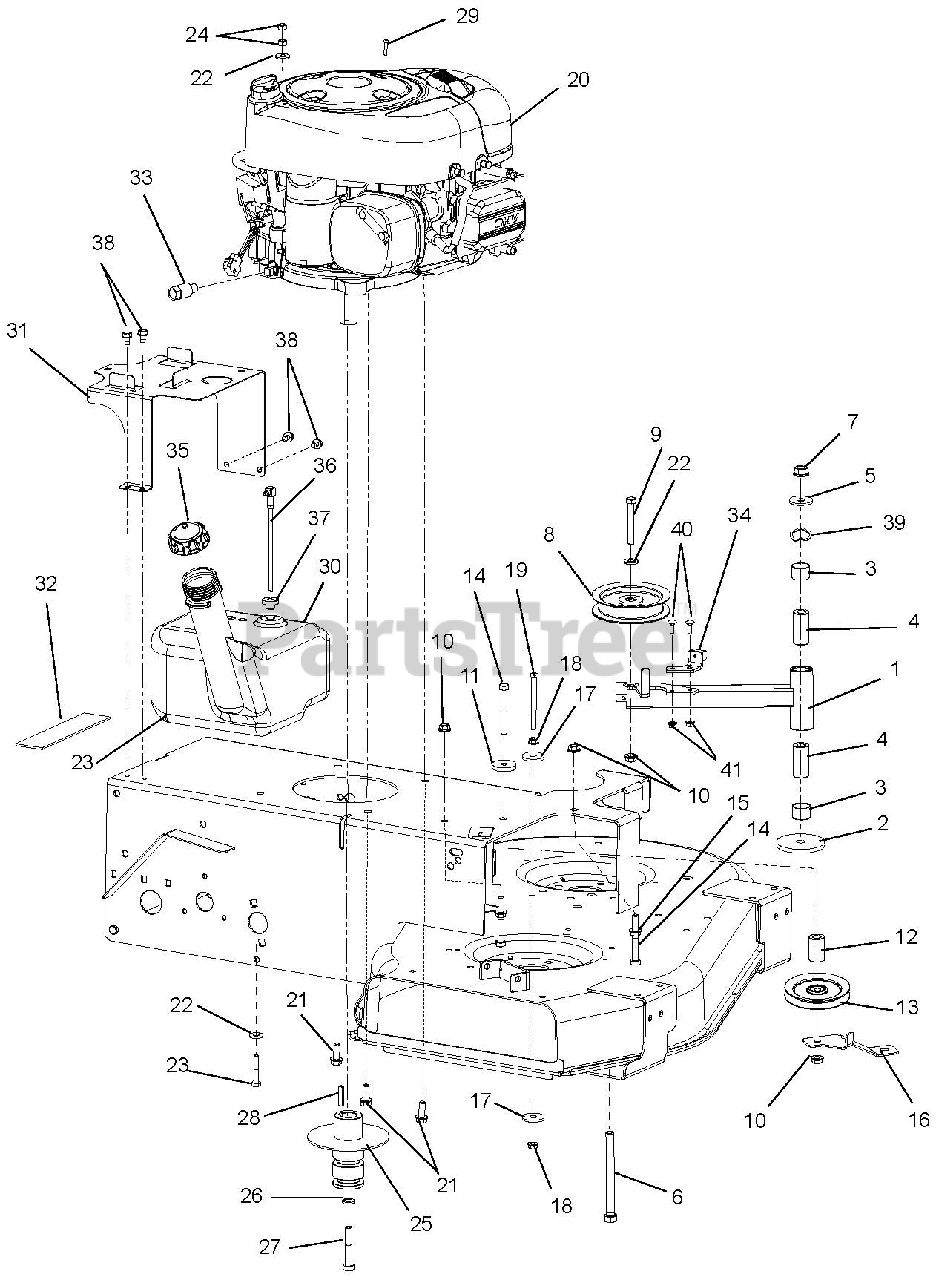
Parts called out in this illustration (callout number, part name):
1	WLDMT, PTO IDLER ARM
2	WASHER, FLAT .531X3.000X.25
3	BRG, 1.00 X 1.12 X .75
4	BSHG, SPCR .502X.997X2.03 PM
5	WSHR-FL-STL.511X1.441X.125 YWZ
6	@BLT-HEX .50-13X5.50 GR5YWZC
7	@NUT-LK-TOP-FLG .50-13 YWZC
8	ASM, IDLER 4"
9	@BLT-HEX .38-16X2.75 GR5 YWZC
10	@NUT-LK-TOP-FLG .38-16 YWZC
11	WSHR,FLT STL.406X1.50X.245YWZC
12	SPACER, .437X1.0X1.23
13	SHV, .38"ID X 4.00"OD V-IDLER
14	@BLT-HEX .38-16X3.00 GR5 YWZC
15	@NUT-SPNLK-FLG .375-16 YWZC
16	BRKT-IDLER BRACE
17	WSHR-FL-STL .406X1.375X.135 YZ
18	@NUT-SPNLK-FLG .312-18 YWZC
19	@BLT-HEX .31-18X3.50 GR5 YWZC
20	ENGINE, 13.5HP BRIGGS IC
21	@SCR-TAP .38-16X1.00 HWH TR YZ
22	@WSHR-FL-STL.38X.875X.083 YWZC
23	@BLT-HEX .31-18X1.75 GR5 YWZC
24	@NUT-LK-CTR .31-18 YWZC
25	PULLEY, PRO-GROUND DRIVE
26	@WSHR-LK .44X.109 REG YWZC
27	BLT-HEX .44-20X2.50 G5 YZ EP80
28	KEY-SQ .25 X 1.25 X .25 SAE
30	TANK, FUEL (BLACK)
31	BRKT, GAS TANK MOUNT
32	PAD, GAS TANK
33	DRAIN, OIL
34	ASSY, WAW WEDGE BRAKE
35	FUEL CAP
36	ASSY-PICKUP, FUEL 6.5L
37	BSHG-FLG .375 X 1.062 X .625 R
38	@SCR-TAP .31-18X.50 HWH TR YWZ
39	WASHER - WAVE 1.09X1.37X.016
40	@BLT-RDHDSQNK .25-20X.75 G5YZ
41	@NUT-LK-TOP-FLG .25-20 YWZC
